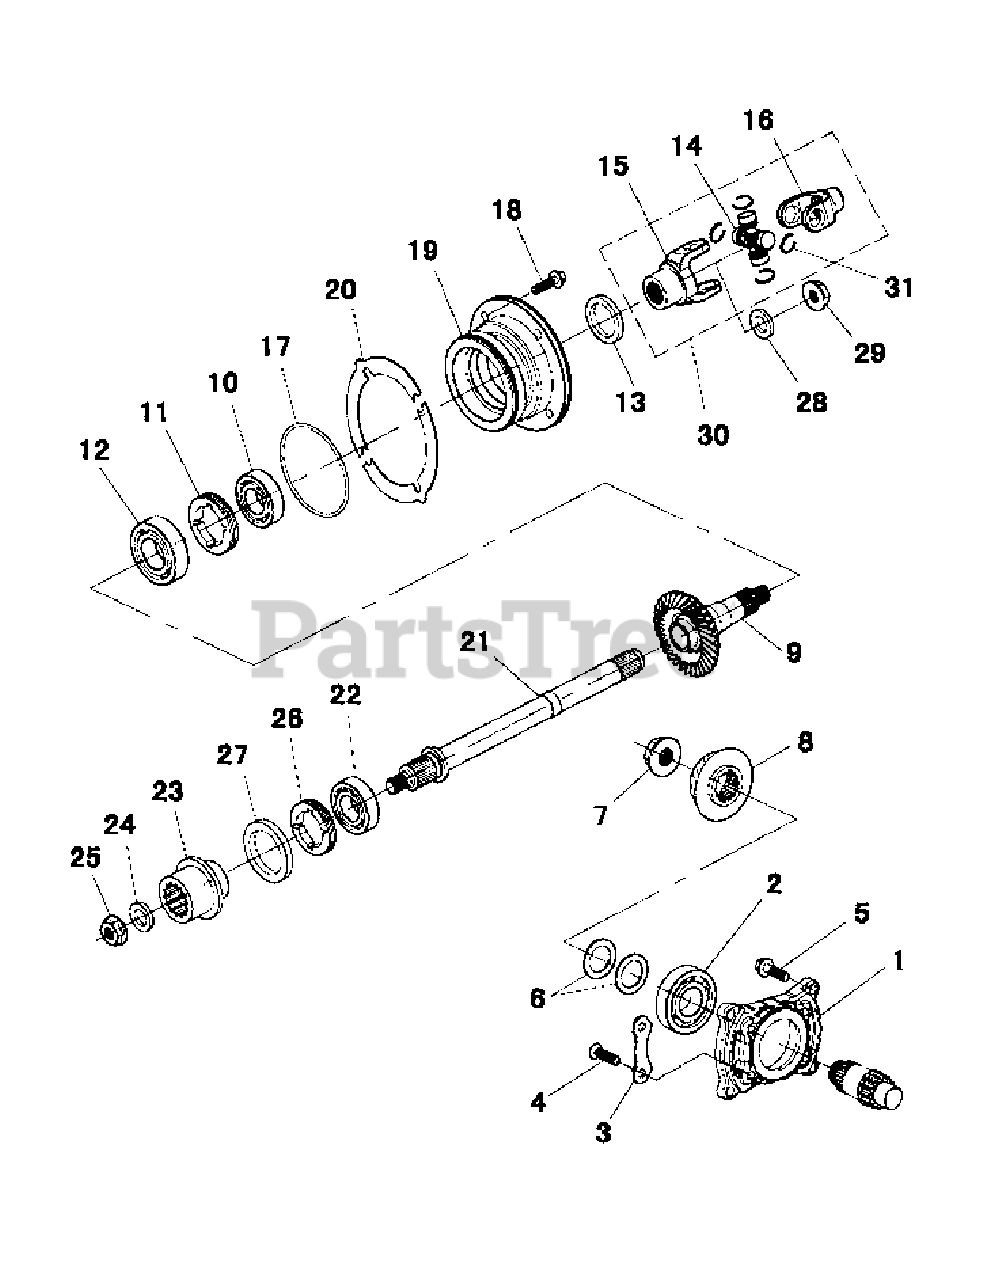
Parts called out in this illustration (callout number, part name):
1	Bearing Seat-Output Shaft
3	Press Plate Bearing
5	Flangebolt M6X30
8	Gear Wheel-Driver Toper
9	Gear Wheel-Driven Toper
11	Locked Ring-M60 X 1.5
14	Crossing
15	Universal Joint A
16	Universal Joint B
17	O-Ring 88X2.8
19	Output Shaft-Bearing Seat
20	Washer
23	Coupling-Flange
26	Lock Ring-M55
27	Seal
30	Universal Joint-Comp
31	Clip
